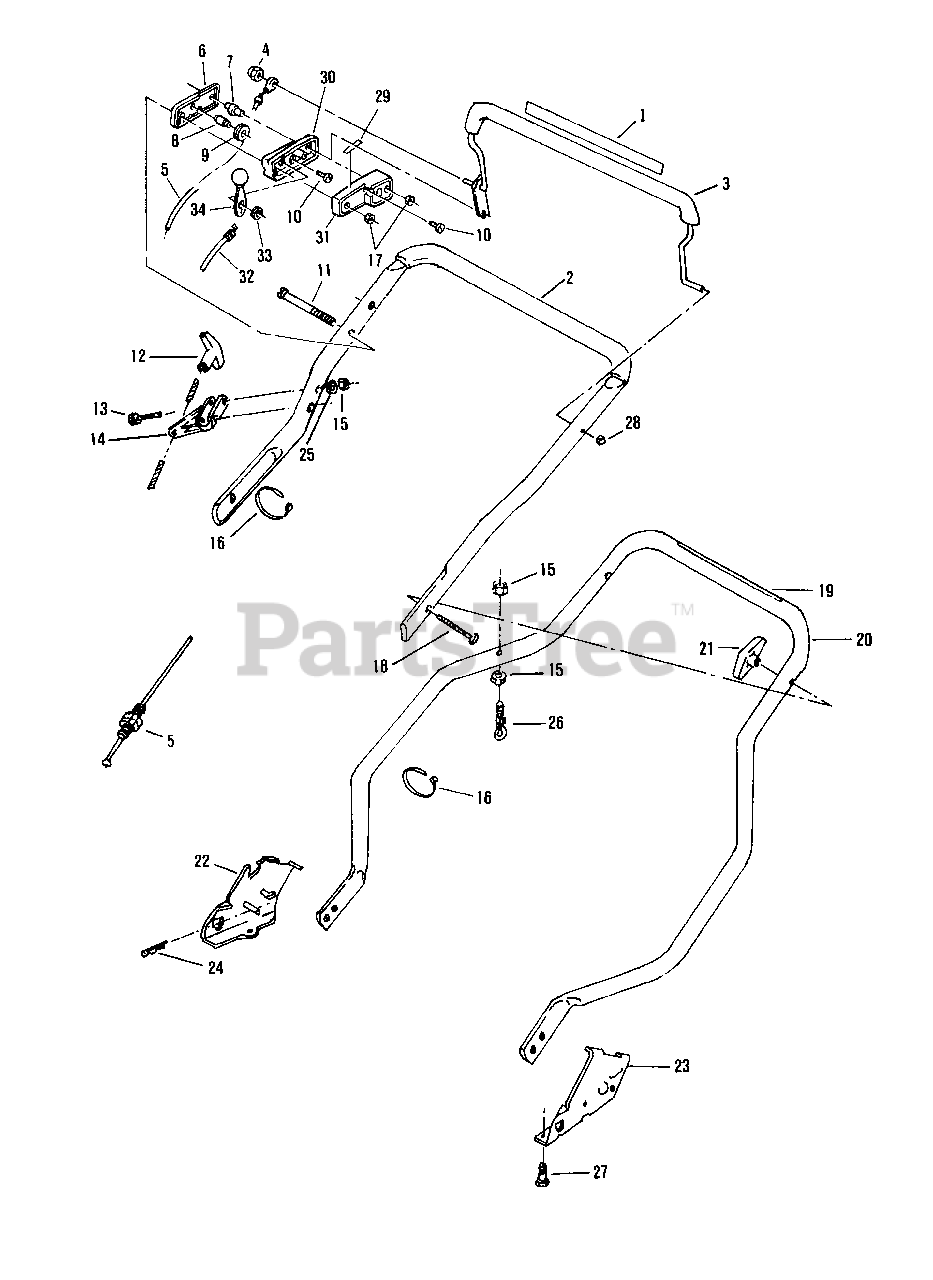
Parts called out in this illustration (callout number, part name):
1	Decal-Engine/Blade Control
2	Top Handle and Grip Assembly
3	Control Lever and Nut Assembly
4	Nut-Acorn
5	Control Cable Assembly
6	Control Case Outer
7	Column
8	Pin
9	Pulley
10	Screw
11	Screw
12	Handle-Starter
13	Screw-Truss Head
14	Rope Guide Assembly
15	Locknut
16	Tie Strap
17	Nut-Hex-Centerlock
18	Screw-Folding Handle
19	Decal-Starting Instructions
20	Handle-Bottom
21	Knob-Folding Handle
22	Bracket-Handle-R.H.
23	Bracket-Handle-L.H.
24	Hair Pin-Handle Bracket
25	Washer
26	Eyebolt
27	Screw-Handle Bracket to Housing
28	Nut-Push
29	Decal-Throttle
30	Case-Throttle-Center
31	Case-Throttle-Inner
32	Throttle Cable
33	Washer-Spring
34	Lever and Knob Assembly
